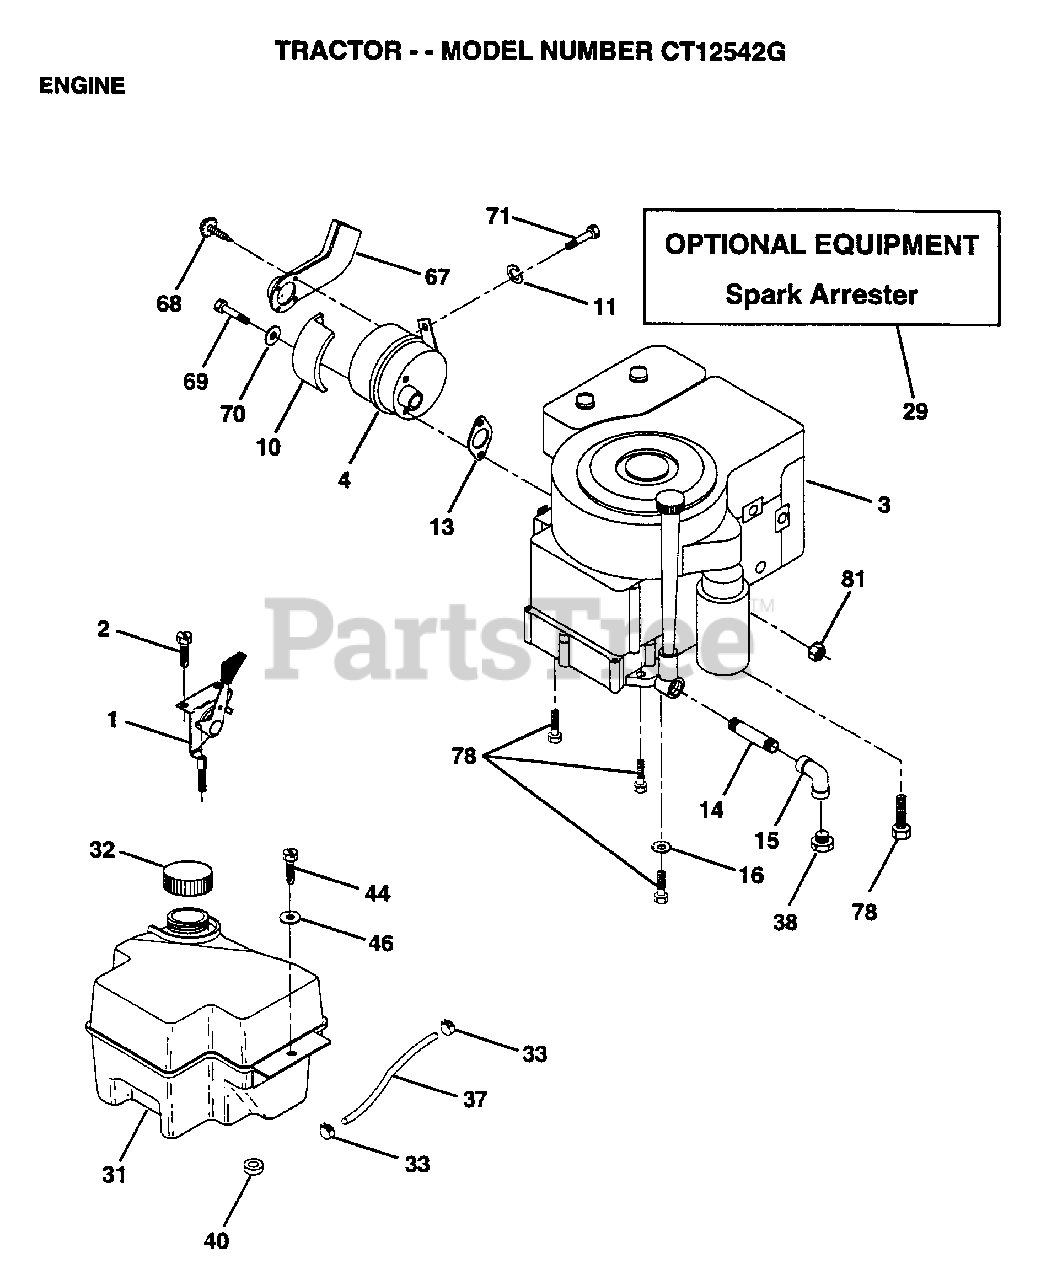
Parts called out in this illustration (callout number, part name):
1	CONTROL THROTTLE
2	SCREW LT
4	MUFFLER LTV
10	SHIELD HEAT LTV
11	LOCKWASHER
14	PIPE NIPPLE
15	ELBOW
16	LOCKWASHER
32	CAP ASM FUEL
33	HOSE CLAMP
37	LINE FUEL
44	SCREW HEX CRT
46	WASHER
67	DEFLECTOR MUFFLER
69	"BOLT,HEX"
70	WASHER T
71	BOLT HXHD FIN
78	SCREW
81	NUT
